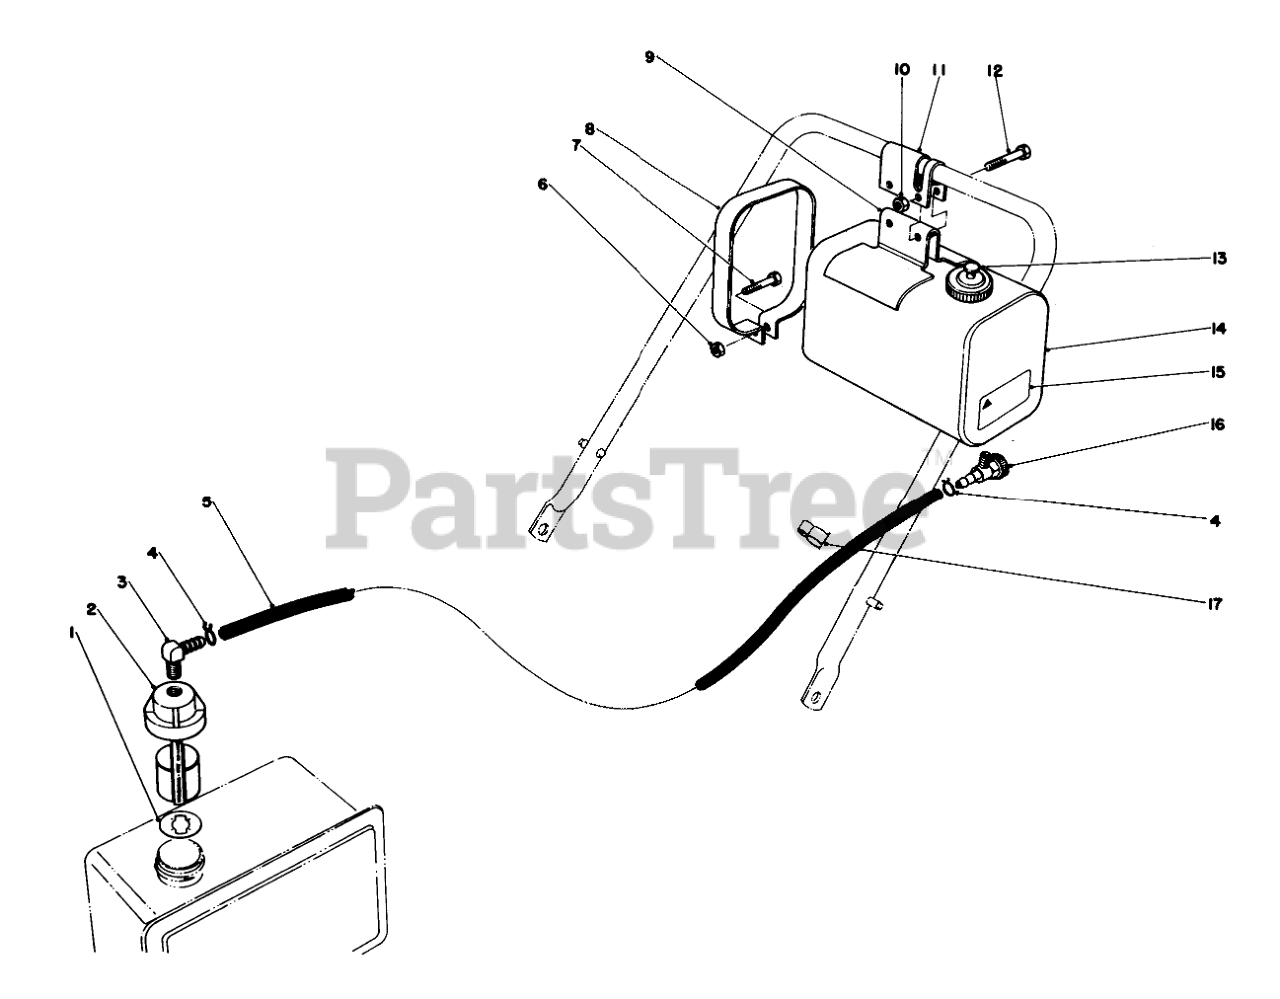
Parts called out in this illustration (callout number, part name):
1	GASKET
2	Fuel Control Valve (Incl. Ref. #1)
3	CONNECTOR-HOSE
4	Clamp
5	FUEL LINE
6	NUT-LOCK
7	SCREW-HH
8	TANK STRAP
9	FUEL TANK BRACKET
10	Nut
11	Clamp
12	SCREW-HH
14	Fuel Tank (Incl. Ref. #13)
15	Decal-Caution
16	.125 ID SHUTOFF VALVE
17	CLAMP
